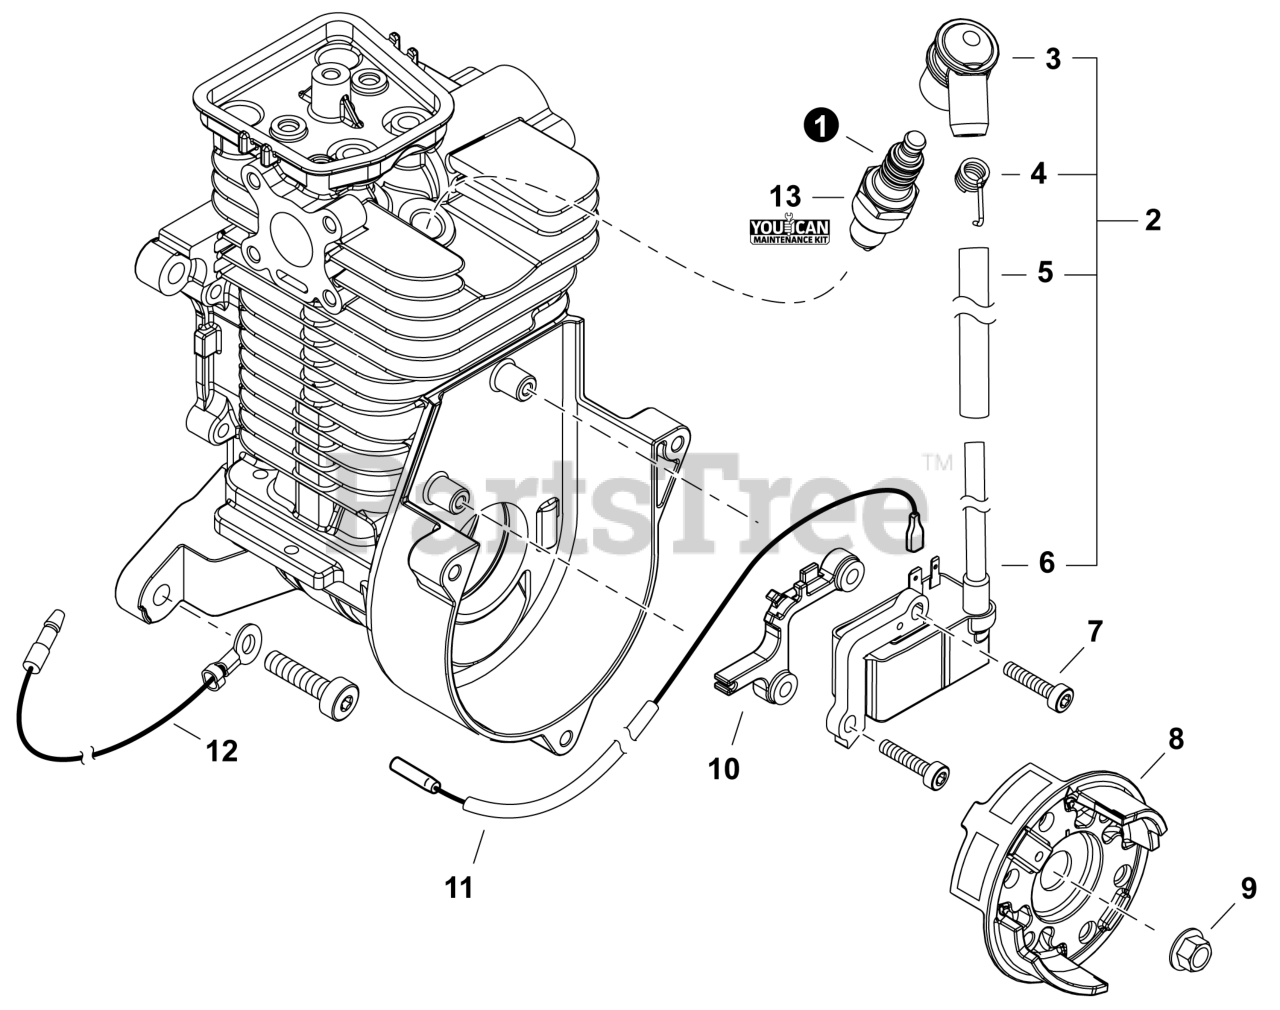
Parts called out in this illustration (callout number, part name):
1	SPARK PLUG - CMR6H
2	COIL ASSY, IGNITION
3	CAP, SPARK PLUG
4	TERMINAL, SPARK PLUG
5	TUBE, INSULATOR 7x75
6	COIL, IGNITION
7	BOLT 4x20
8	FLYWHEEL
9	NUT, FLANGE 10x1.25
10	INSULATOR, HEAT
11	LEAD - IGNITION
12	LEAD - GROUND
13	TUNE-UP KIT - YOUCANT
